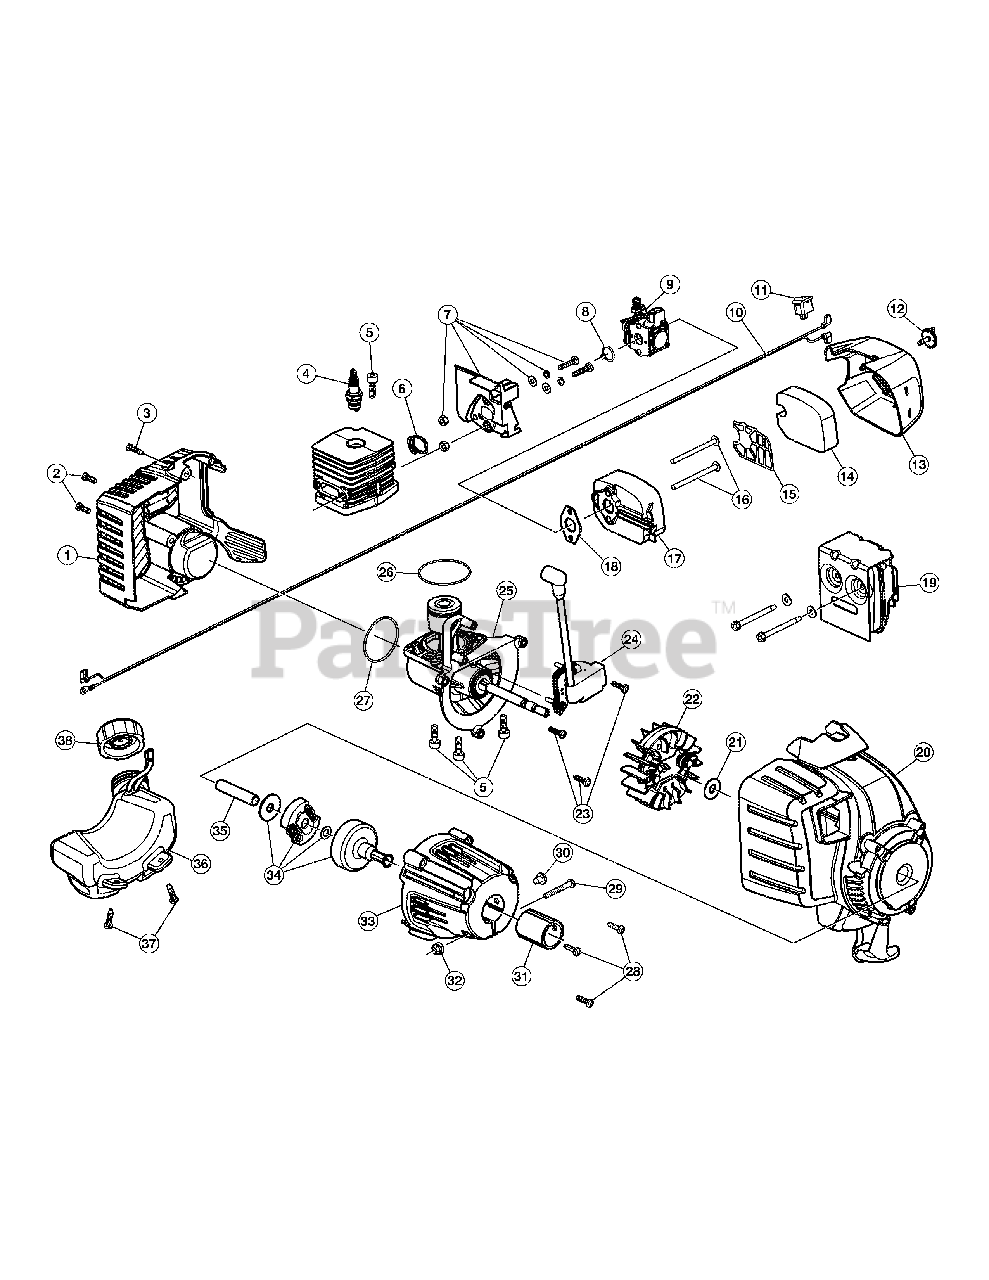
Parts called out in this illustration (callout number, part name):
1	Rear Housing Assembly (Incl. 2 and 3)
2	Screw
4	Spark Plug
6	Insulator O-Ring
7	Insulator Assembly (Incl. 6 and 8)
8	Carburetor O-Ring
9	Carburetor
10	Lead Wire
13	Air Cleaner Cover
14	Air Filter
17	Air Cleaner Base
18	Gasket
19	Muffler Assembly
20	Starter Housing Assembly
21	Washer
22	Flywheel
23	Screw
24	Module Assembly
25	Shortblock (Incl. 4, 5, 19, 21, 22, 23)
26	Crankcase O-Ring
27	O-Ring
29	Clamp Screw
31	Rubber Spacer
33	Clutch Cover
34	Clutch Assembly
35	Spacer
36	Fuel Tank (Incl. 37 and 38)
37	Fuel Tank Screw
38	Fuel Tank Cap
